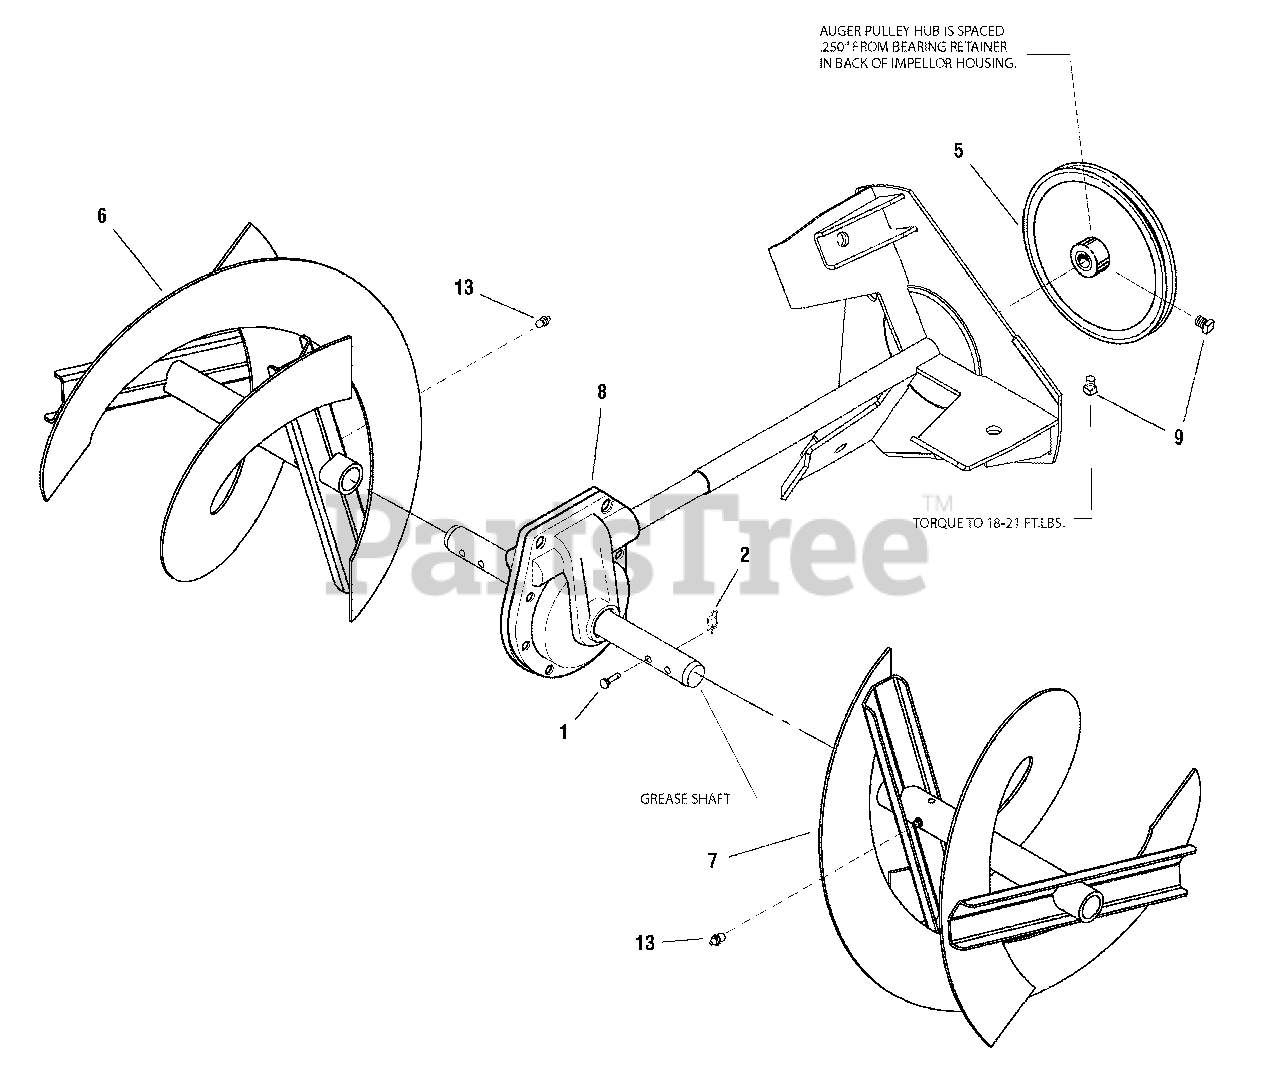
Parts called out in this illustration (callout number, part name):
1	PIN, SHEAR
2	COTTER PIN, 1/4" Self Locking
5	PULLEY, w/Hub
6	AUGER ASSEMBLY, 24" & 26" R.H.
7	AUGER ASSEMBLY, 24" & 26" L.H.
8	GEAR BOX ASSEMBLY KIT
9	SCREW, Set, Square Head Cup Point 5/16-18 x 1/2 G8
13	FITTING, Lube, 1/4 Drive, No Check Ball
